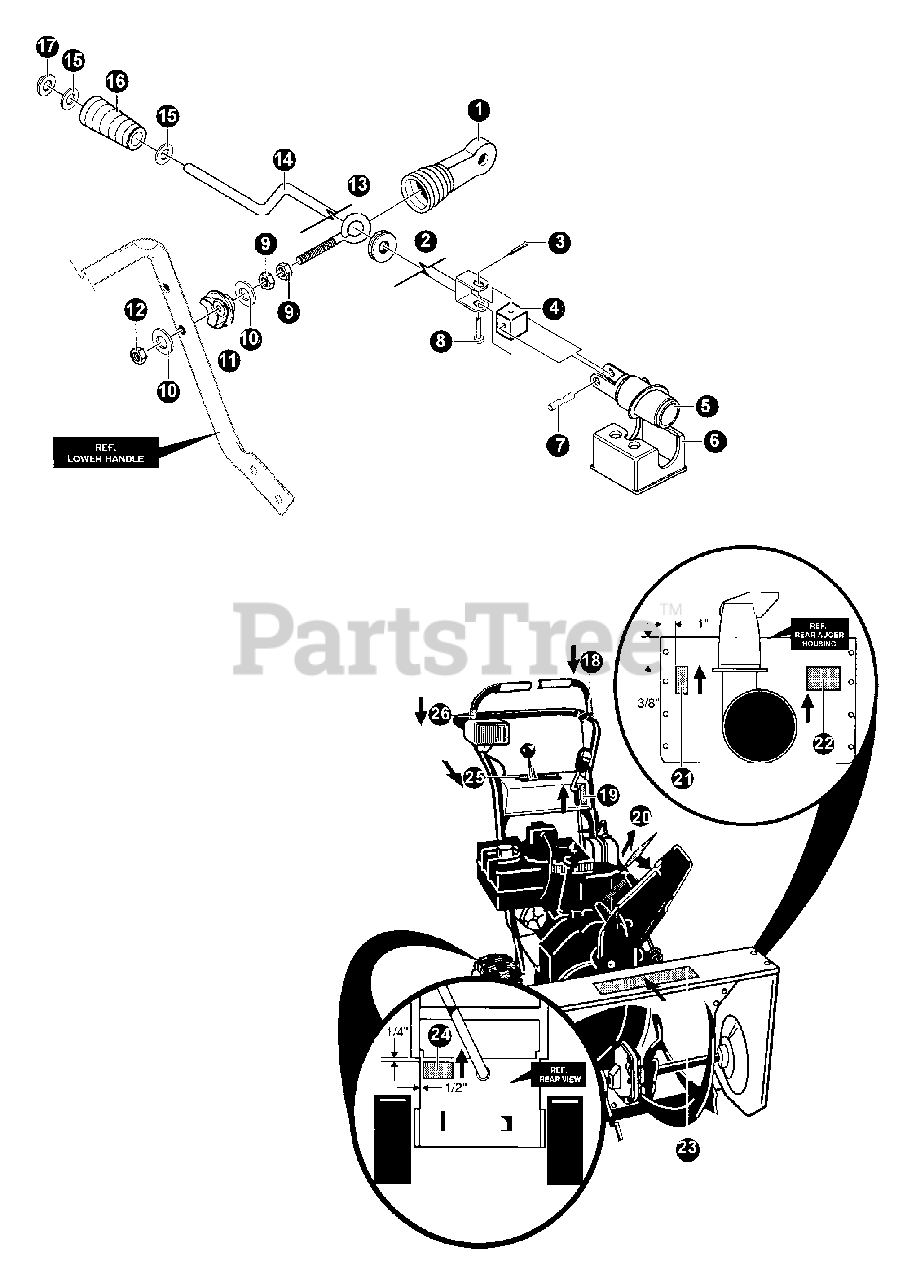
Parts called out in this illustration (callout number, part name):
1	BOOT, EYEBOLT CHUTE
2	GROMMET, EYE BOLT
3	PIN, SPLIT
4	BLOCK, UNIV PIV
5	GEAR - WORM
6	BRACKET, WORM MTG
7	PIN, U-JOINT
8	PIN, CLEVIS
9	NUT - 3/8-16
10	WASHER
11	ADAPTOR, BOOT
12	LOCKNUT - 3/8-16
13	BOLT - 3/8-16X5 -- EYE
14	CRANK, CHUTE
15	WASHER, FLAT .39X.70X.05
16	HANDLE, CHUTE CRANK
17	RING, RETAINING
18	LABEL - TRACTION DRIVE ENGAGE
19	LABEL - REMOTE CHUTE
20	LABEL - DANGER
21	LABEL - DANGER
22	LABEL - DANGER
23	LABEL - ECHO
25	LABEL - GEAR SELECTOR
26	LABEL - AUGER DRIVE ENGAGE
